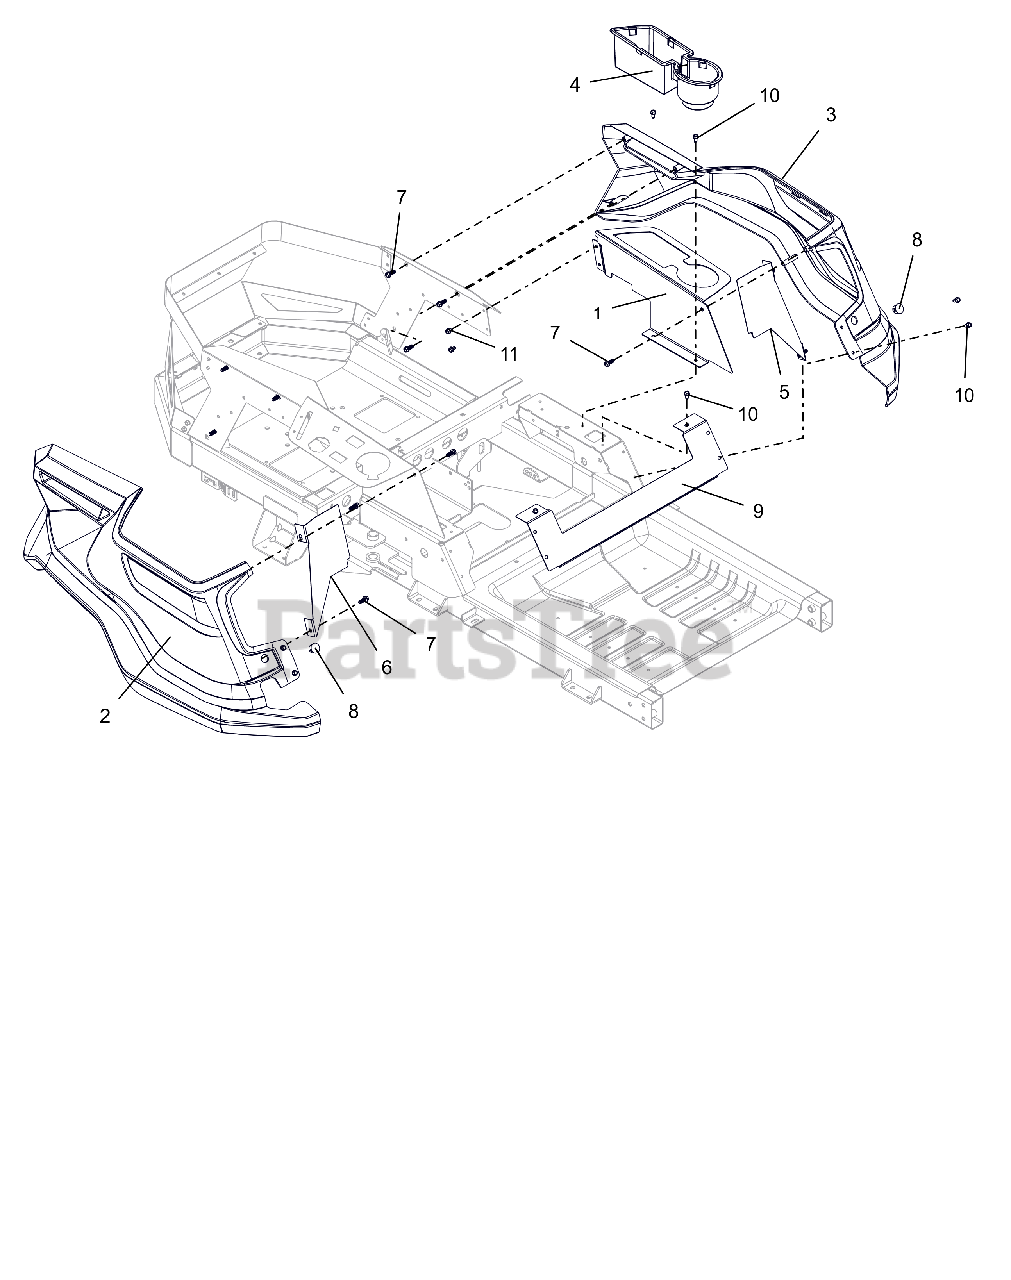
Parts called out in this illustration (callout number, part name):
1	PANEL, LEFT SIDE FENDER MOUNT
2	FENDER, RH IKON
3	FENDER, LH IKON
4	INSERT, CUP/STORAGE HOLDER
5	PLATE, LH BLOCKER
6	PLATE, RH BLOCKER
7	SCR-.312X.75 #14H H/W/H H/L CZ
8	PLUG, HOLE .75 (BLACK)
9	PLATE, SEAT KICK
10	SCR-TAP .25-20X.50 HWH ZCC
11	SCR,TAP .25-20X.375 HWH TR ZCC
